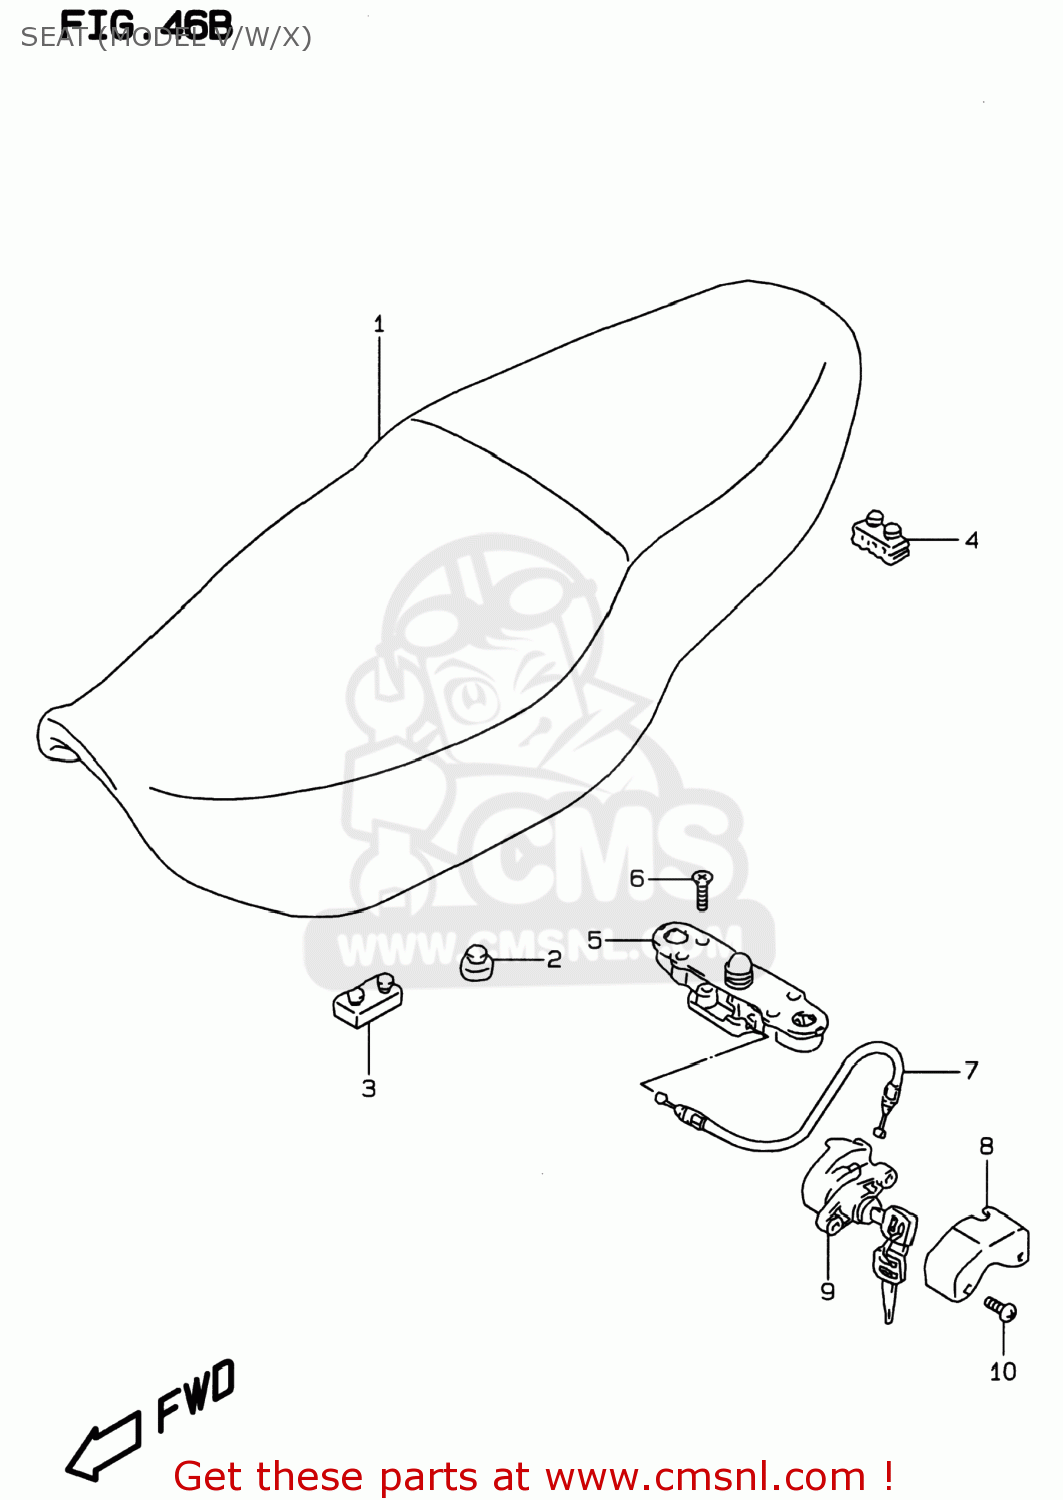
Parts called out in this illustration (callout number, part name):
1	SEAT ASSEMBLY (BLACK)
2	CUSHION
3	CUSHION
4	CUSHION,SEAT(40X20X15)
5	LOCK ASSY,SEAT STRIKER
6	SCREW 6X30
7	CABLE,SEAT LOCK
8	GUARD,SEAT LOCK
9	LOCK SET,SEAT
10	SCREW(6X14)
